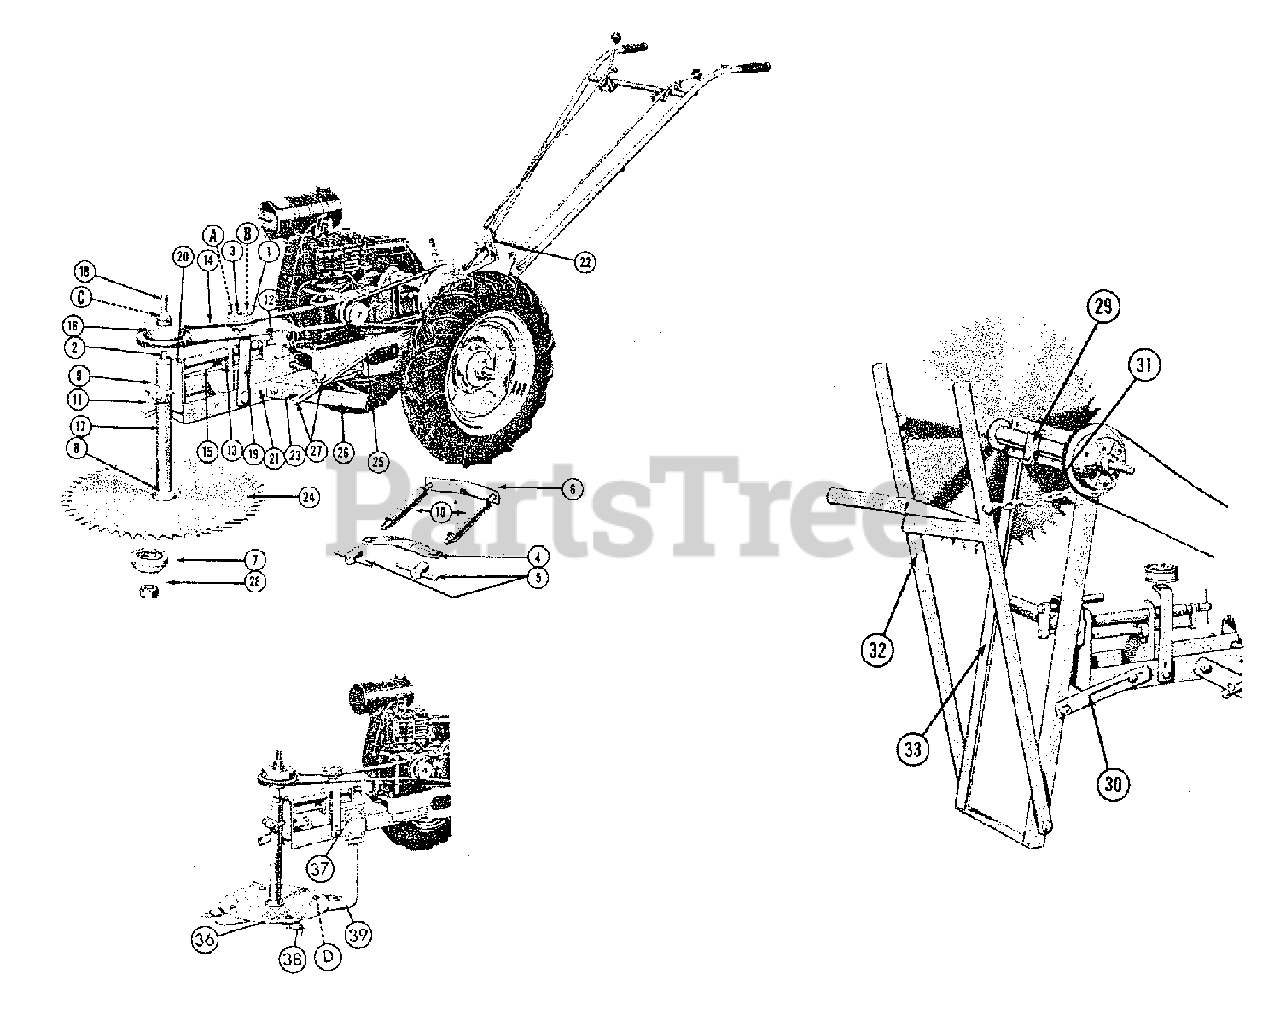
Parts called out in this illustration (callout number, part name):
1	PULLEY, Idler
2	COLLAR, Set (Arbor Shaft)
3	PULLEY, Idler, Thrust Washer
4	SIDE PLATE, Hitch
6	CLAMP ASSEMBLY, Hitch
7	FLANGE, Lower
8	FLANGE, Upper
11	PROP, Arbor
12	SCREW, Tightener
13	COLLAR, Set (Tightener Assembly)
15	TIGHTENER ASSEMBLY
16	CLUTCH ASSEMBLY
17	BEARING, Housing w/ Bushings
19	BRACKET, Idler
20	HOLDER ASSEMBLY, Arbor
21	FRAME ASSEMBLY
22	CLIP, Spring
23	PIN ASSEMBLY, Rod Socket
24	SAW BLADE, 20" Cordwood (1-3/8" Bore)
25	ROD, Stand
27	COLLAR, Set (Stand Rod)
28	NUT, Hex, Full, L.H.
30	HOLDER, Cradle
31	CHAIN, Cradle, 12"
32	CRADLE ASSEMBLY
33	FRAME ASSEMBLY, Cradle
36	HEAD, Knife
37	CLAMP PLATE, Gauge
39	SHOE ASSEMBLY, Gauge
A	INNER BEARING RACE
B	BEARING, Idler Pulley
C	KEY, Pulley
